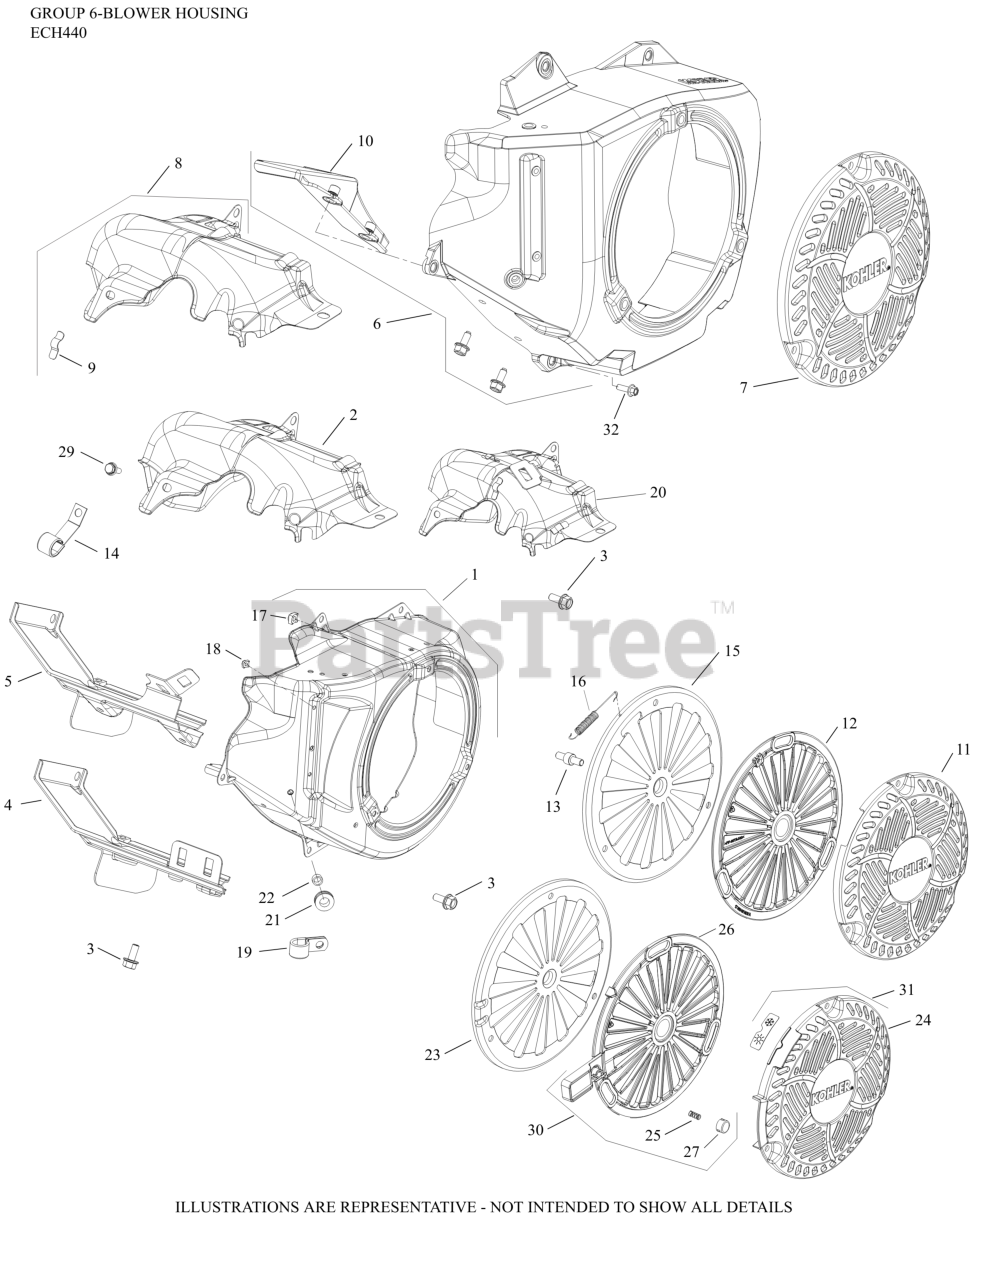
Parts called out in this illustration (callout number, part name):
1	KIT, BLOWER HOUSING
2	SHIELD, UPPER HEAT
4	SHIELD ASSEMBLY, CYLINDER
8	HEAT SHIELD ASSEMBLY
14	CLIP, CABLE
